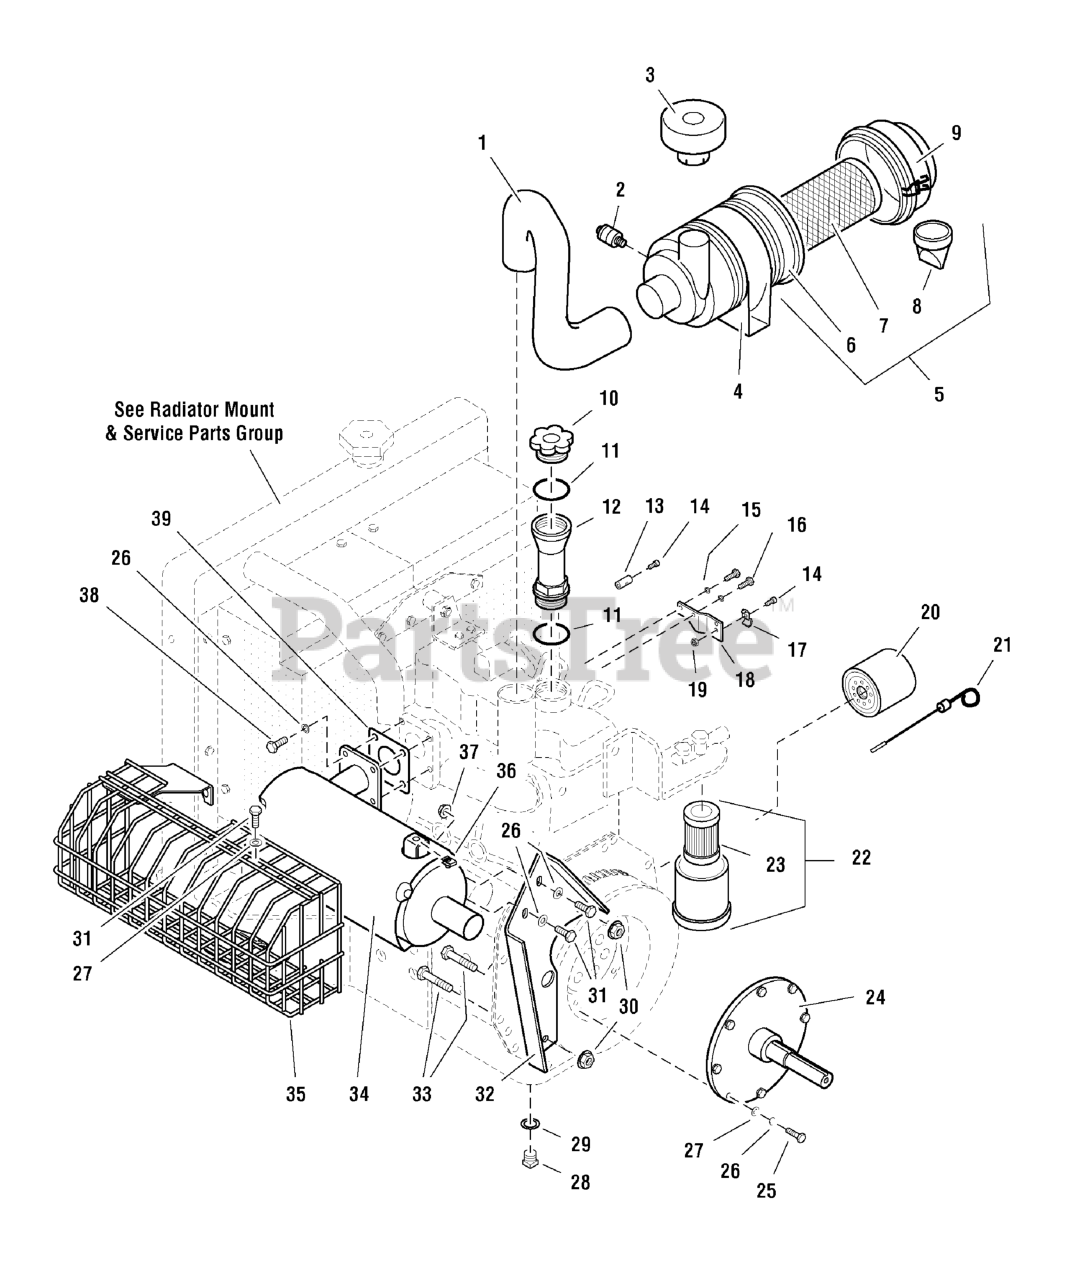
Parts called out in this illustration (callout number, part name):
1	AIR INLET HOSE
2	AIR CLEANER INDICATOR
3	PRE-CLEANER
4	AIR CLEANER BRACKET
5	AIR CLEANER ASSEMBLY, Complete
6	AIR CLEANER HOUSING ASSEMBLY
7	AIR CLEANER ELEMENT
8	AIR CLEANER DUST VALVE
9	AIR CLEANER COVER
10	OIL FILL CAP
11	OIL FILL O-RING SEAL
12	OIL FILL EXTENSION
13	BARREL CLAMP
14	SCREW, #10-24 x 3/4
15	WASHER, 1/4 LOCK
16	BOLT, M6 x 10MM
17	CLAMP
18	THROTTLE BRACKET
19	NUT, #10-24 Hex Nylon Lock
20	OIL FILTER
22	FUEL FILTER ASSEMBLY, Complete
23	FILTER ELEMENT
25	BOLT, 5/16-18 x 1-1/4
26	WASHER, 5/16 LOCK CZ
27	WASHER, 5/16" SAE
28	OIL PAN PLUG
29	WASHER, Oil Pan Plug
30	NUT, 3/8-16 Hex Serrated Flange
31	BOLT, 5/16-18 X 1 GD5 YZ
32	MUFFLER SUPPORT
33	BOLT, 3/8-16 X 1-3/4" GD5 CZ
34	USE - 5100556 - MUFFLER, 3013C CAT DIE
35	WELD, MUFFLER GUARD - BLK
36	BODY CLIP, 5/16-18-7GA MATERIAL
37	NUT, 5/16-18 HEX SERRATED FLANGE (SMALL)
38	BOLT, M8-1.25 X 25MM GR 8.8
39	GASKET, EXHAUST MANIFOLD - NET
40	FUEL SOLENOID
41	WASHER, Fuel Solenoid
42	WATER PUMP
43	WATER HOSE-UPPER
44	WATER HOSE-LOWER
45	GASKET, Water Pump
46	THERMOSTAT
47	GASKET, Thermostat
48	STARTER MOTOR
49	ALTERNATOR
50	BELT
51	FUEL PUMP,# 295-4070 - NET
52	GASKET, Fuel Pump
53	GLOW PLUG
54	RADIATOR
55	SWITCH, Oil Pressure
56	SWITCH, Water Temperature
57	STARTER SOLENOID
58	SEAL, REAR MAIN - NET
59	SEAL, Front Main
60	INJECTOR ASSEMBLY
61	WASHER, 4-HOLE
62	WASHER, SEALING
63	WASHER, CRUSH
64	CLAMP, RADIATOR HOSE
65	GASKETS, VALVE COVER
66	PARTS MANUAL, ENGINE
